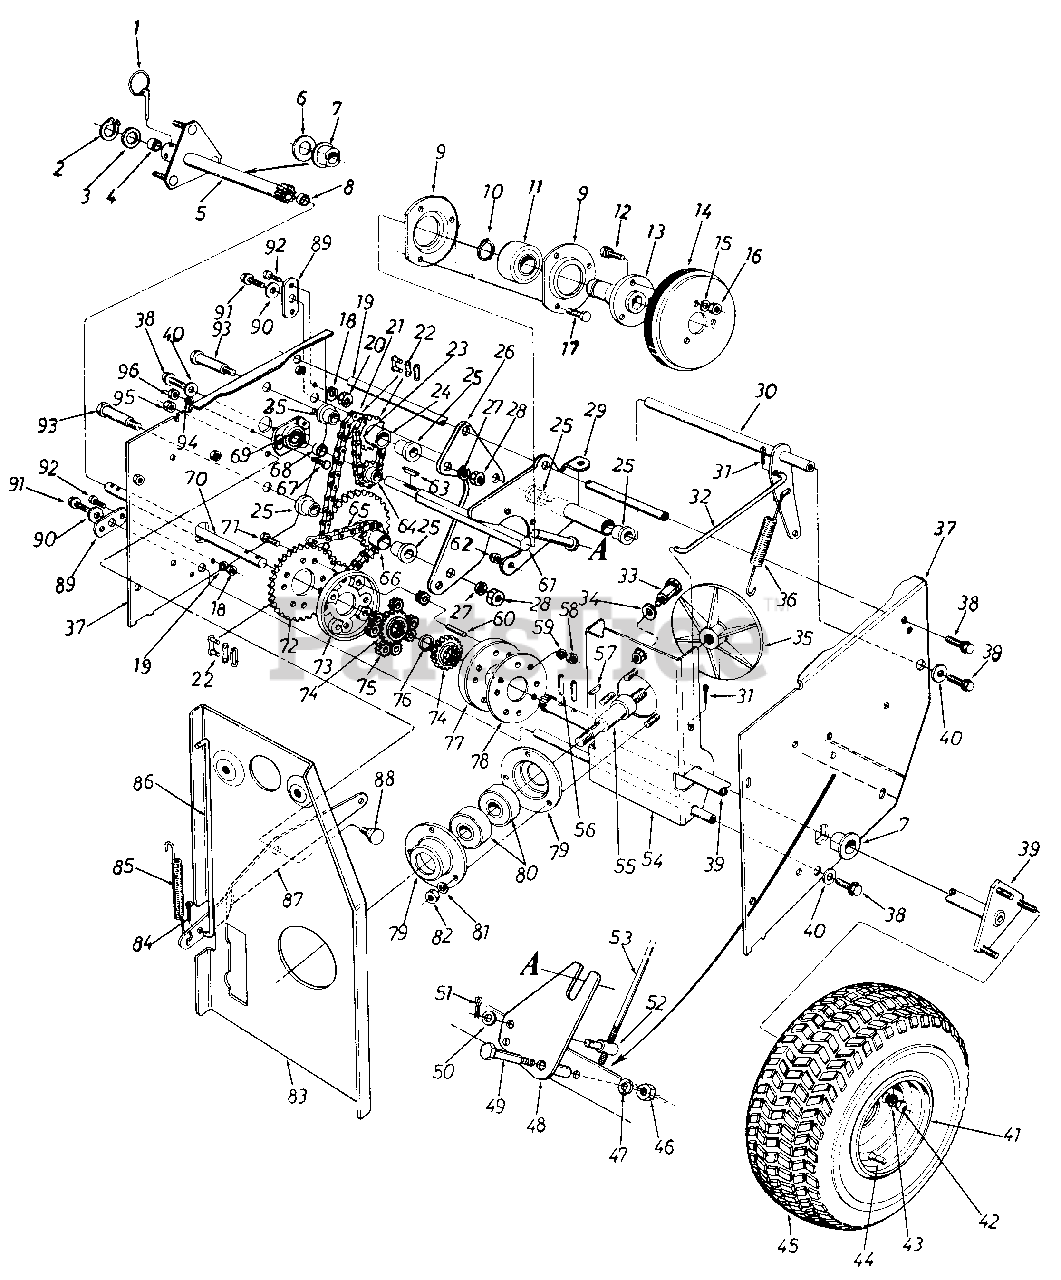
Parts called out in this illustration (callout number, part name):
1	Klick Pin 1/4" Dia. x 1.75"
2	Snap Ring .625" Shaft
3	Fl-Wash. .62" I.D. x 1.25"
4	Sleeve Brg.
5	Differential Tubing Ass'y.-R.H.
6	Fl-Wash. .62" I.D. x 1.25"
7	Flange Brg. w/Flats 1" I.D.
8	Sleeve Brg.
9	Bearing Housing
10	Snap Ring-1.00" Dia.
11	Ball Brg. .25MM x 52MM x 15MM Thk.
12	Hex Sems Bolt 5/16-18 x .75" Lg.*
13	Friction Wheel Adapter
14	Friction Wheel Ass'y.
15	L-Wash. 5/16" I.D.
16	Hex Nut 5/16-18 Thd.
17	Hex Bolt 1/4-28 x .62" Lg.
18	L-Wash. 1/4" I.D.
19	Sliding Support Axle
20	Hex Nut 1/4-20 Thd.
21	#41 Chain-1/2" Pitch x 43 Links
22	Master Link
23	#41 Chain-1/2" Pitch x 19 Links
24	9 and 14 Teeth Sprocket Hub Ass'y.
25	Flange Brg. .630" I.D.
28	Hex L-Jam Nut 3/8-24 Thd.
29	Sliding Brkt. Ass'y.
30	Drive Clutch Brkt. Ass'y.
31	Inter. Cot. Pin 5/16" Dia.
32	Drive Clutch Rod .31" Dia. x 7.38" Lg.
33	Shld. Bolt
34	Bell-Wash. .44" I.D. x .88"
35	Aluminum Drive Plate
36	Extension Spring 4.31" Lg.
37	Frame Ass'y.
38	Hex L-Bolt 5/16-18 x .62"
39	Differential Shaft Ass'y.
40	Fl-Wash. .345" I.D. x .75"
41	Rim Only-16"
42	Cone Nut 3/8-24 Thd.
43	L-Wash. 3/8" I.D.-H.D.
44	Tubeless Air Valve
45	Wheel Ass'y. Comp. 16 x 6.5
46	Hex Jam Nut 3/8-16 Thd.
47	L-Wash. 3/8" I.D.
50	Fl-Wash. .344" I.D. x .62"
51	Cotter Pin 3/32" Dia. x .75"*
52	Adjustment Ferrule
53	Shifting Rod
56	H-Spring Pin Spiral 3/16" Dia. x 1.25" Lg.
57	#61 Hi-Pro Key 3/16 x 5/8" Dia.
58	Hex Nut 1/4-28 Thd.
59	L-Wash. 1/4" I.D.*
60	Differential Pin
61	Hex Shaft
62	Hex L-Nut 1/4-28 Thd.
63	#9 Hi-Pro Key 3/32 x 5/8" Dia.
64	8 Teeth Sprocket
65	#420 Chain-.50 Pitch x 37 Links
66	9 and 32 Teeth Sprocket Hub Ass'y.
67	Hex Bolt 1/4-20 x .62" Lg.*
68	Spacer .51" I.D. x .69" O.D.
69	Ball Bearing
70	Differential Connecting Shaft
71	Hex Bolt 1/4-28 x 1.75" Lg.*
72	28 Teeth Sprocket
73	Differential Housing
74	20 Tooth Spur Gear
75	9 Tooth Spur Gear
76	Fl-Wash. .62" I.D. x 1.25"
77	Differential Housing
78	Differential Hsg. Support Plate
79	Bearing rlousing
80	Ball Brc. .787" I.D. x 1.85"
81	L-Wash. 5/16" I.D.*
82	Hex Nut 5/16-18 Thd.*
83	Engine Brkt. Ass'y.
84	Inter. Cotter Pin 5/16" Dia.
85	Extension Spring .38" O.D. x 3.18" Lg.
86	Auger Clutch Rod .31" Dia. x 10.62" Lg.
87	Auger Clutch Brkt.
88	Shld. Bolt .625" Dia. x .170"
89	Pivot Axle Brkt.
90	Fl-Wash. .345" I.D. x .75"
91	Hex L-Bolt 5/16-18 x .62"
92	Hex Bolt 1/4-20 x .62" Lg.*
93	Sprocket Hub Tubing 1.88"
94	L-Wash. 1/4" I.D.*
95	Hex Cent. L-Nut 3/8-16 Thd.
96	Hex Nut 1/4-20 Thd.*
